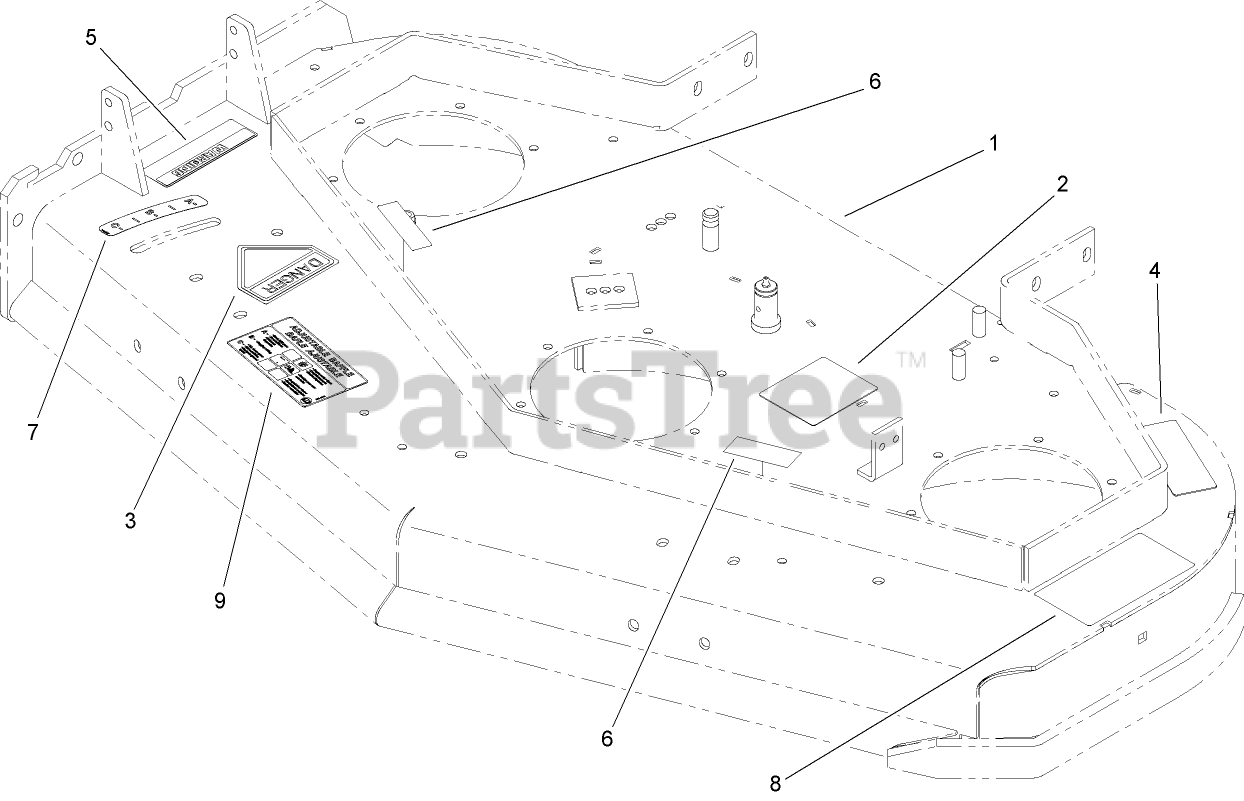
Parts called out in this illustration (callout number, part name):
1	48 INCH DECK ASM
2	DECAL-ROUTING, BELT
3	DECAL-DANGER
4	DECAL-TORQUE, BOLT
5	DECAL-WARNING
6	DECAL-COVER, MISSING
7	DECAL-SETTING, BAFFLE
8	DECAL-DANGER, THROWN OBJECT
9	DECAL-ADJUSTMENT, BAFFLE
